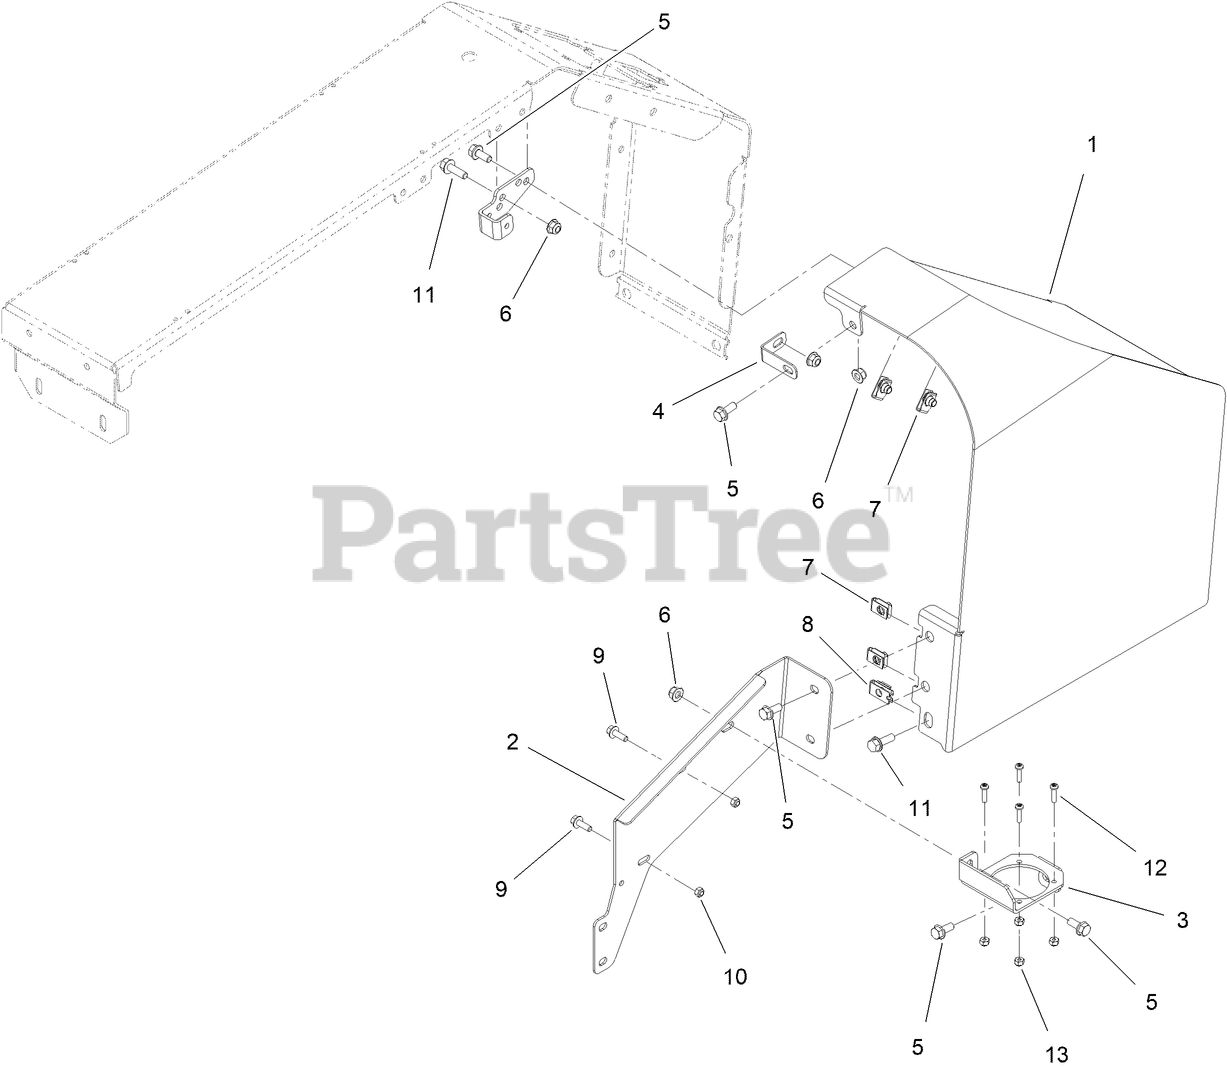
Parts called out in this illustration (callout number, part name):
1	CONSOLE COVER-LEFT (TORO RED)
2	FUSE MOUNT
3	BRACKET-DISCONNECT
4	BRACKET-COVER
5	SCREW-HHF
6	NUT-HF, NI
7	NUT-U
8	NUT-THICK, TINNERMAN
9	SCREW-HHF
10	LOCKNUT (1/4-NF, NYL INSERT)
11	SCREW-HHF
12	SCREW-TORX
13	NUT-LOCK, NI
